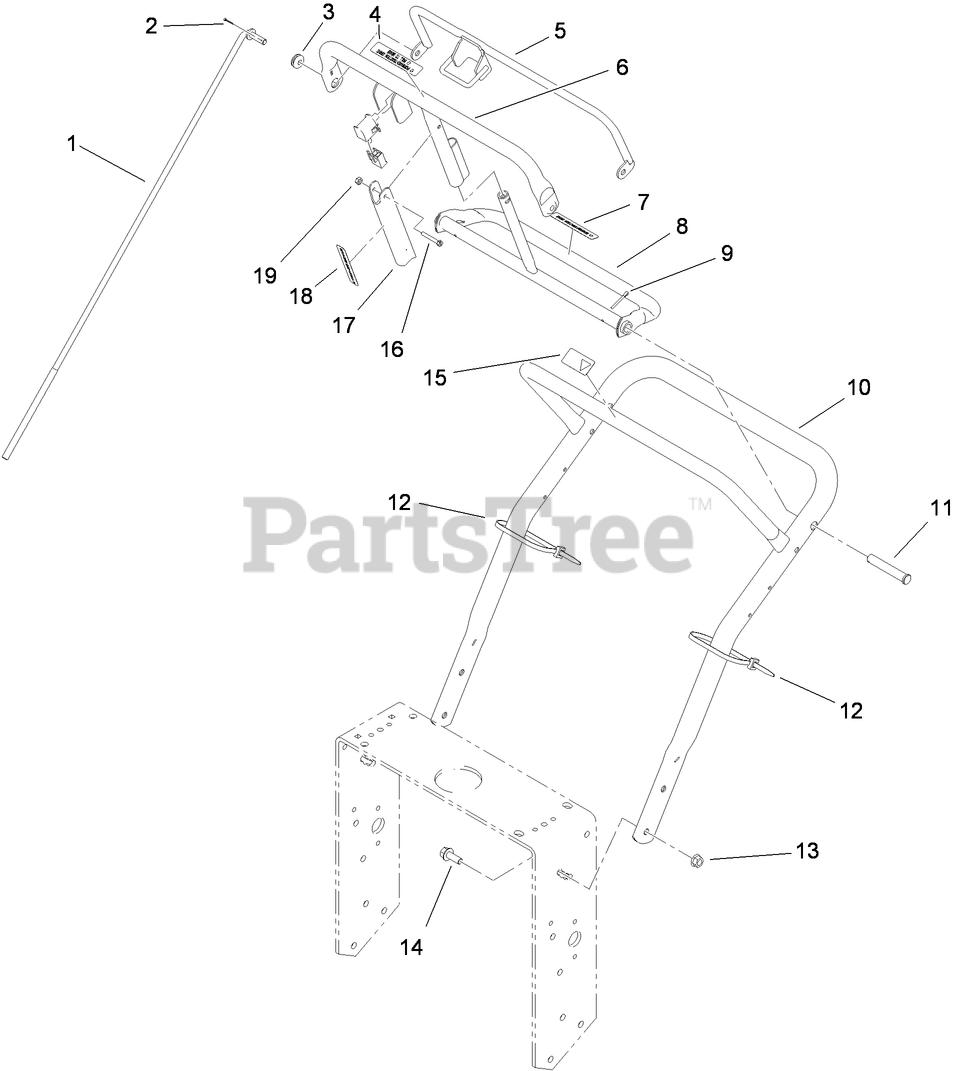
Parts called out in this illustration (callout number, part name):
1	ROD-CONTROL
2	PIN-COTTER
3	GROMMET-RUBBER
4	DECAL
6	BAR-CONTROL
7	DECAL
8	PIVOT-CONTROL
9	PIN-COTTER
10	HANDLE-UPPER
11	PIN-CLEVIS
12	TIE-CABLE
13	NUT-HF
14	SCREW-HHF
15	DECAL-PROTECTION, EAR
16	SCREW-SHH
17	LEVER-BRAKE, PARKING
18	DECAL-LEVER, PARKING
19	NUT-LOCK, NI
